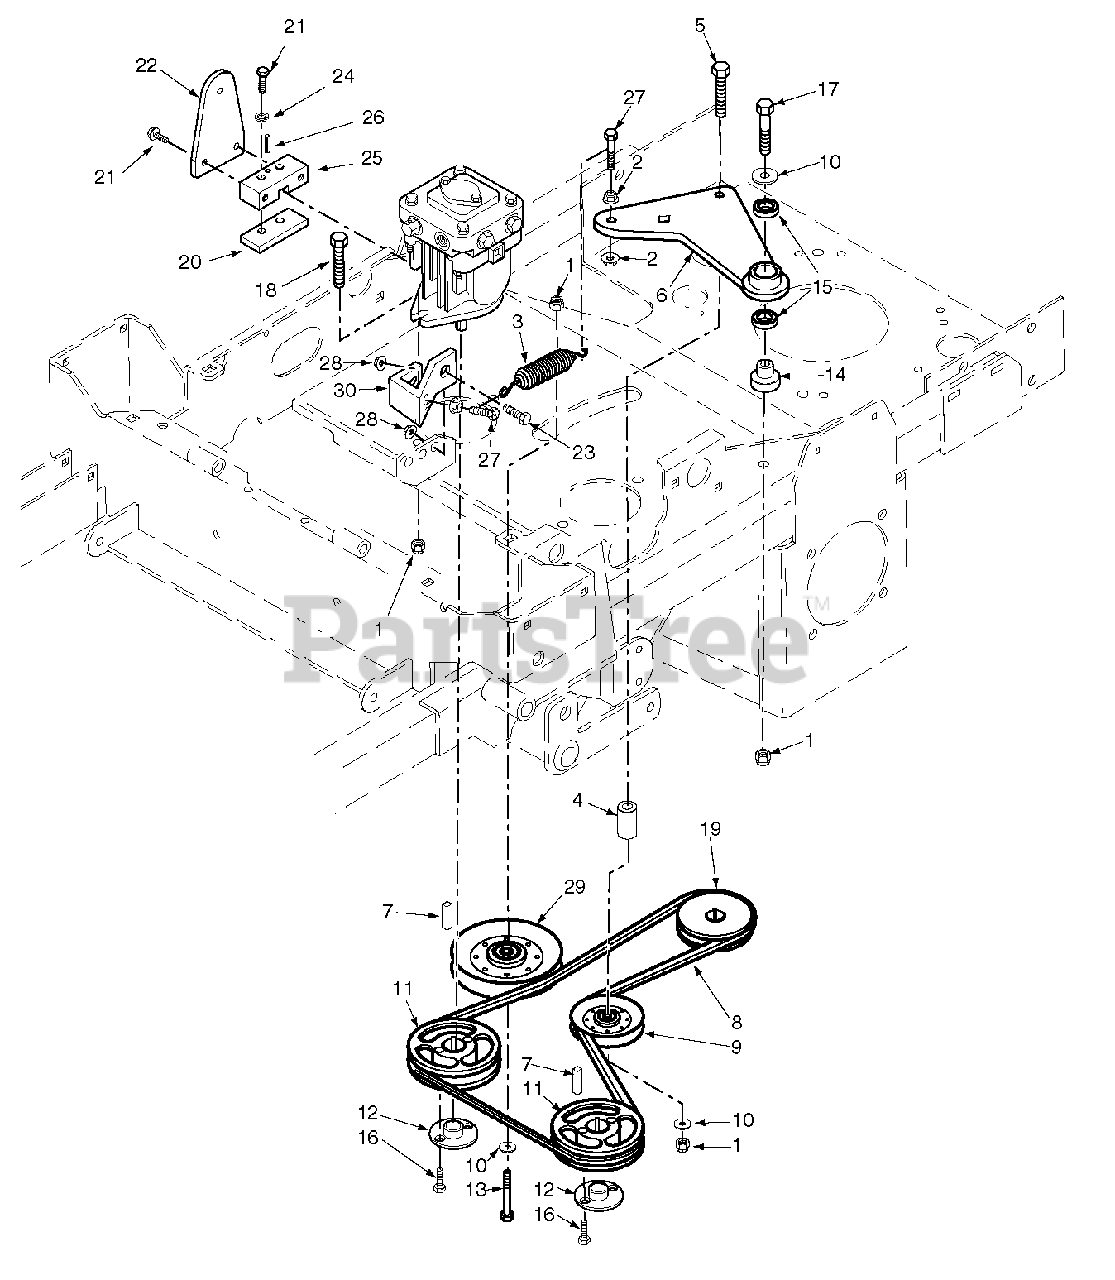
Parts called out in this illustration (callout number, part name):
1	Nut, Elastic Stop 3/8-16
2	Nut, Serr. Flng. 3/8-16
3	Spring, Pump Idler
4	Spacer
5	Bolt, Hex Hd. 3/8-16 x 2-3/4"
6	Idler Arm Assy., Pump Drive
7	Key, 5 x 5 x 25mm
8	Belt, Transmission
9	Pulley, 3-1/2" Dia. Idler
10	Flatwasher, 3/8 (.391 x .938 x .105")
11	Pulley, 5.75" OD Taper Bore
12	Hub, Tapered, 15mm Bore
13	Bolt, 3/8-16 x 2"
14	Pivot, Idler
15	Bearing
16	Bolt, Hex Hd. 1/4-20 x 1" Grd. 8
17	Bolt, Hex Hd. 3/8-16 x 2-1/2"
18	Bolt, Hex Hd. 3/8-16 x 1-1/2"
19	Pulley, 5.75" Dia. - 1.125" Bore
20	Clamp Plate
21	Hex Hd. Capscrew, 1/4-20 x 3/4"
22	Control Lever, Pump
23	Bolt, Hex Hd. 3/8-16 x 1"
24	Lockwasher, 1/4"
25	Block, Pump Control
26	Roll Pin
27	Bolt, Hex Hd. 3/8-16 x 1-1/2" Grd. 8
28	Nut, Serr. Flng. 3/8-16
29	Pulley, 5" Dia. Idler
30	Bracket
